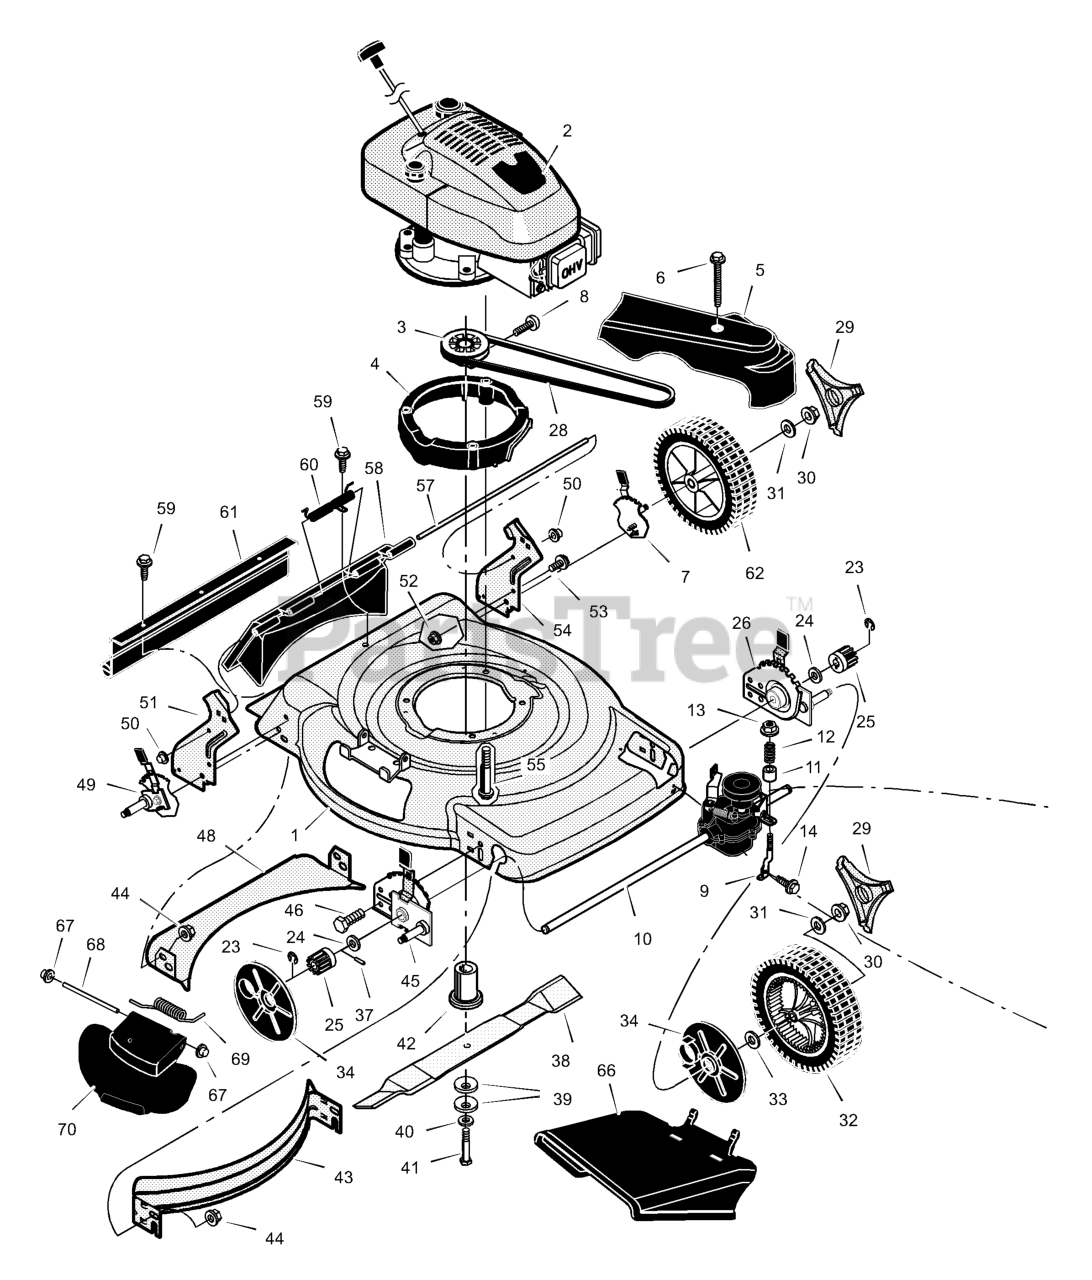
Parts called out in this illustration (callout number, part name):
1	Housing
2	Engine *
3	Pulley, Drive
4	Spacer, Engine
5	Cover, Belt (Black)
7	Adjuster, Left Rear Height
9	Support, Spring
10	Transmission *
12	Spring, Compression
13	Nut
25	Gear, Pinion
26	Adjuster, Left Front Height
29	Cap, Hub
30	Nut, Flange
31	Washer
32	Wheel & Tire, Front
34	Cover, Dust
37	Pin, Drive
39	Washer, Belleville
42	Adapter, Blade
43	Baffle, Front
44	Nut, Flange
45	Adjuster, Right Front Height
46	Bolt
48	Baffle, Rear
49	Adjuster, Right Rear Height
50	Push On Cap
51	Bracket, Right Handle
52	Nut, Flange
53	Bolt
54	Bracket, Left Handle
55	Bolt, Engine
57	Rod, Pivot
58	Door, Rear (Black)
60	Spring
61	Guard, Rear
62	Wheel & Tire, Rear
66	Deflector, Chute
67	Push On Cap
68	Rod, Pivot
69	Spring, Torsion
70	Cover, Mulch (Black)
